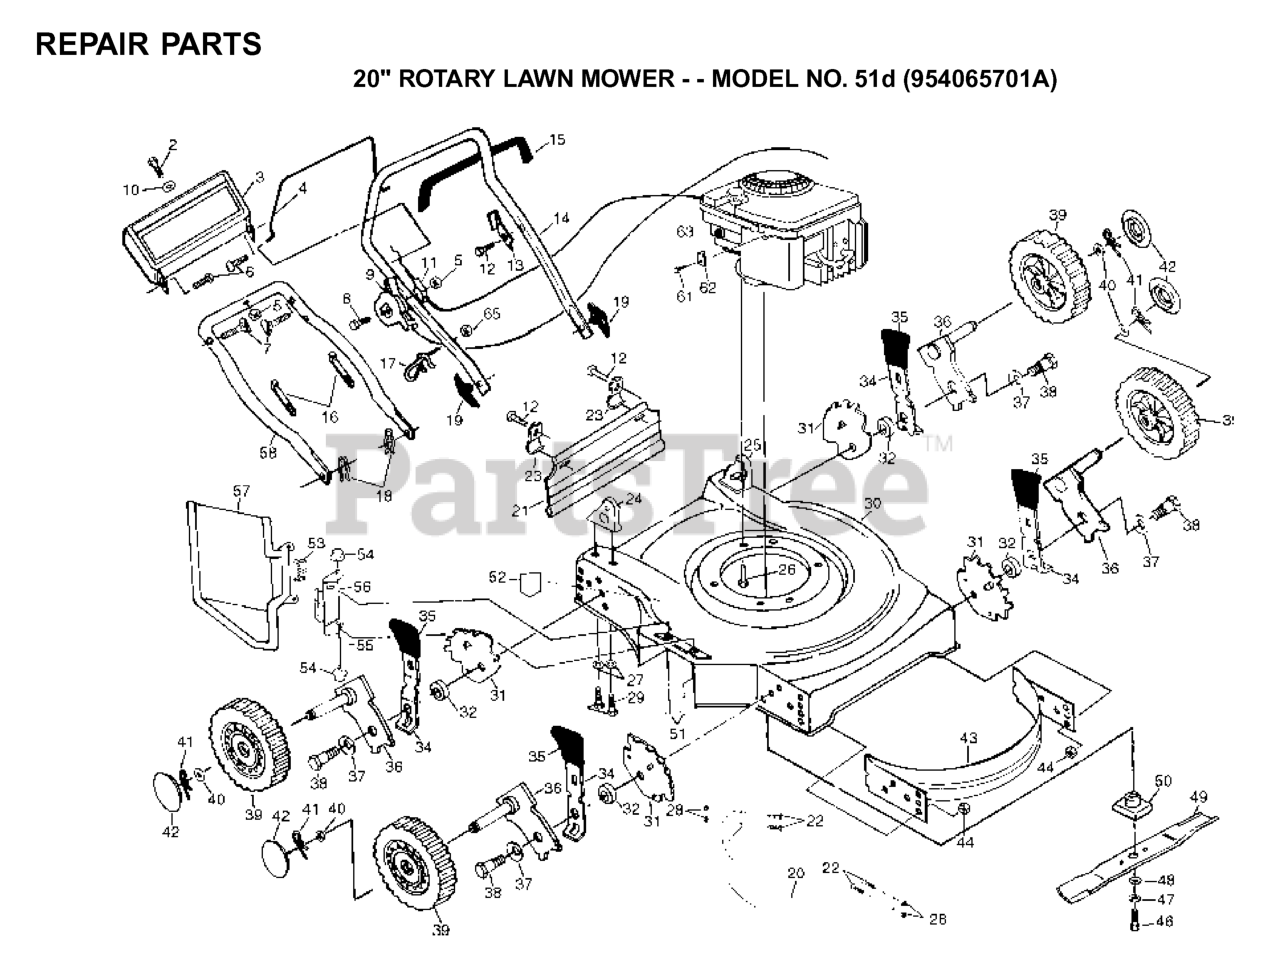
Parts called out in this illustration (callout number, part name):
2	SCREW
3	TRIM PLATE
4	CONTROL BAR/BLACK
5	NUT
7	HANDLE BOLT
8	SCREW 1/4-20 X 2.12
9	THROTTLE CONTROL
11	CABLE.MZR.51.RT.SP./PU.
12	TAPPING SCREW
13	BRACKET UPSTOP
14	UPPER HANDLE
15	HANDLE GRIP
16	TIE GUIDE
17	ROPE GUIDE
18	HAIRPIN COTTER
19	HANDLE KNOB
21	REAR SKIRT
23	BRACKET DEFL PM
24	HANDLE BRKT ASSY RH
25	HANDLE BRKT ASSY LH
26	BOLT
27	STEEL WASHER
29	SCREW
31	WHEEL ADJUST BRACKET
32	SPACER PM
34	SELECTOR SPRING
35	SELECTOR KNOB
36	AXLE ARM
37	WASHER.BELLEVILLE (3 2 LB)
38	BOLT
39	PACKAGE.WHEEL.8 X 2 RADIAL
41	RETAINER CLIP PM
43	BAFFLE
44	LOCKNUT PM
46	SCREW, HEX HD 3/8-24 X 1-3/8
47	LOCKWASHER
48	WASHER,HARDEN
49	BLADE 20" MULCH
50	BLADE ADAPTOR
51	SCREW
52	DECAL HYT
53	SPRING TENSION
54	PUSH-ON SPEED NUT
55	ROD HINGE
56	BRKT HSG
58	HANDLE, LOWER PM
61	SCREW.HEX.HEAD.WASHER.10-16
65	NUT
